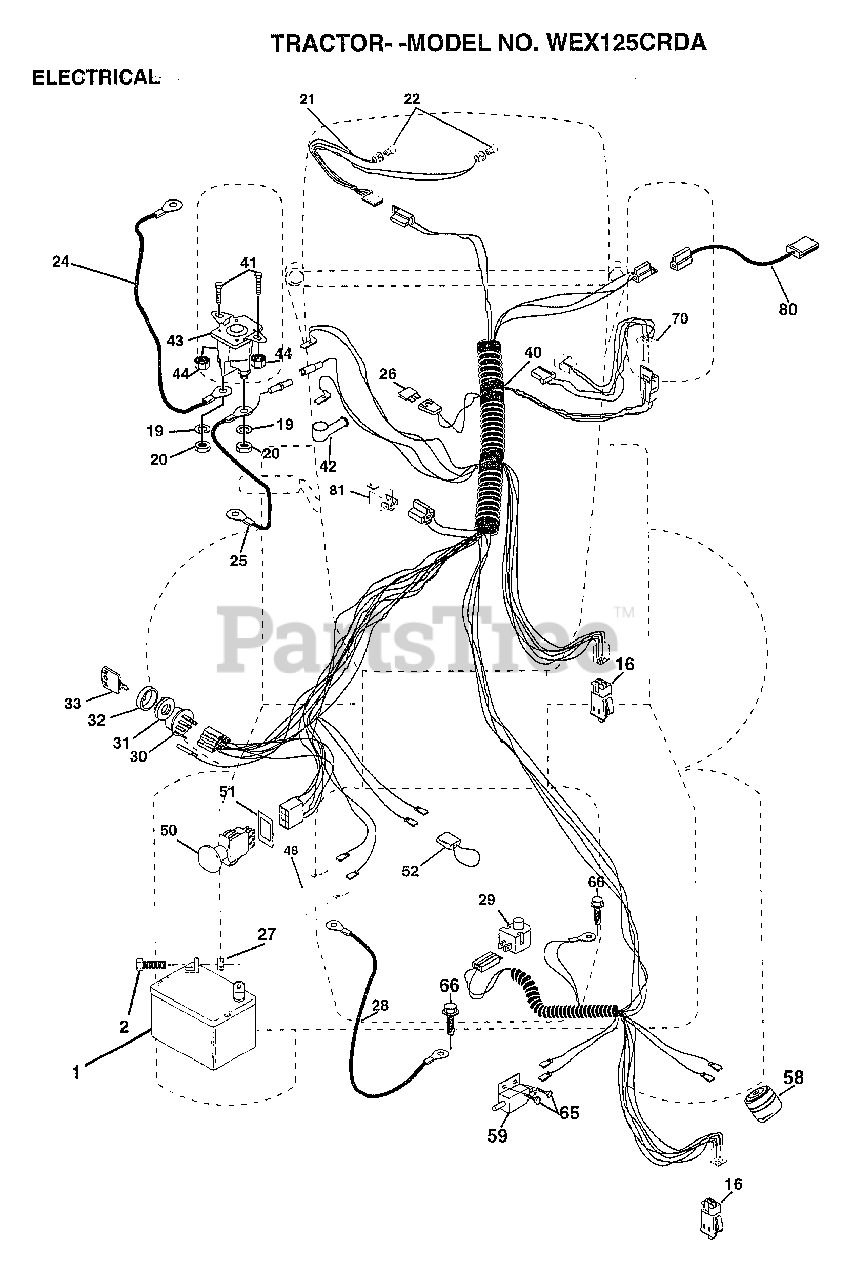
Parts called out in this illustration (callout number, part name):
2	BOLT LT
16	SWITCH INTERLOCK
20	NUT
21	HARNESS.ASM.LIGHT W/4152J
22	HEADLAMP BULB
24	"CABLE T, BATTERY"
25	CABLE.BATTERY.CRD
26	FUSE.15 AMP
27	NUT
28	"CABLE.GRD.6GA/18""BLACK"
29	SWITCH.PLUNGER
30	SWITCH IGN 4POS
31	NUT IGNITION
32	COVER KEY SWITCH
33	KEY
40	HARNESS.IGN.CRD.ELECT
41	BOLT HXHD FIN
44	NUT HXKEP 1/4X20
48	ADAPTER AMMETER
50	PTO SWITCH.BLK
51	RING RETAIN PTO
52	PROTECTION LOOP
59	SWITCH.FBI.CRD
65	SCREW
66	SCREW LT
70	HARNESS.ENGINE
80	HARNESS.CLUT.EVX.
81	RELAY ASSY T
